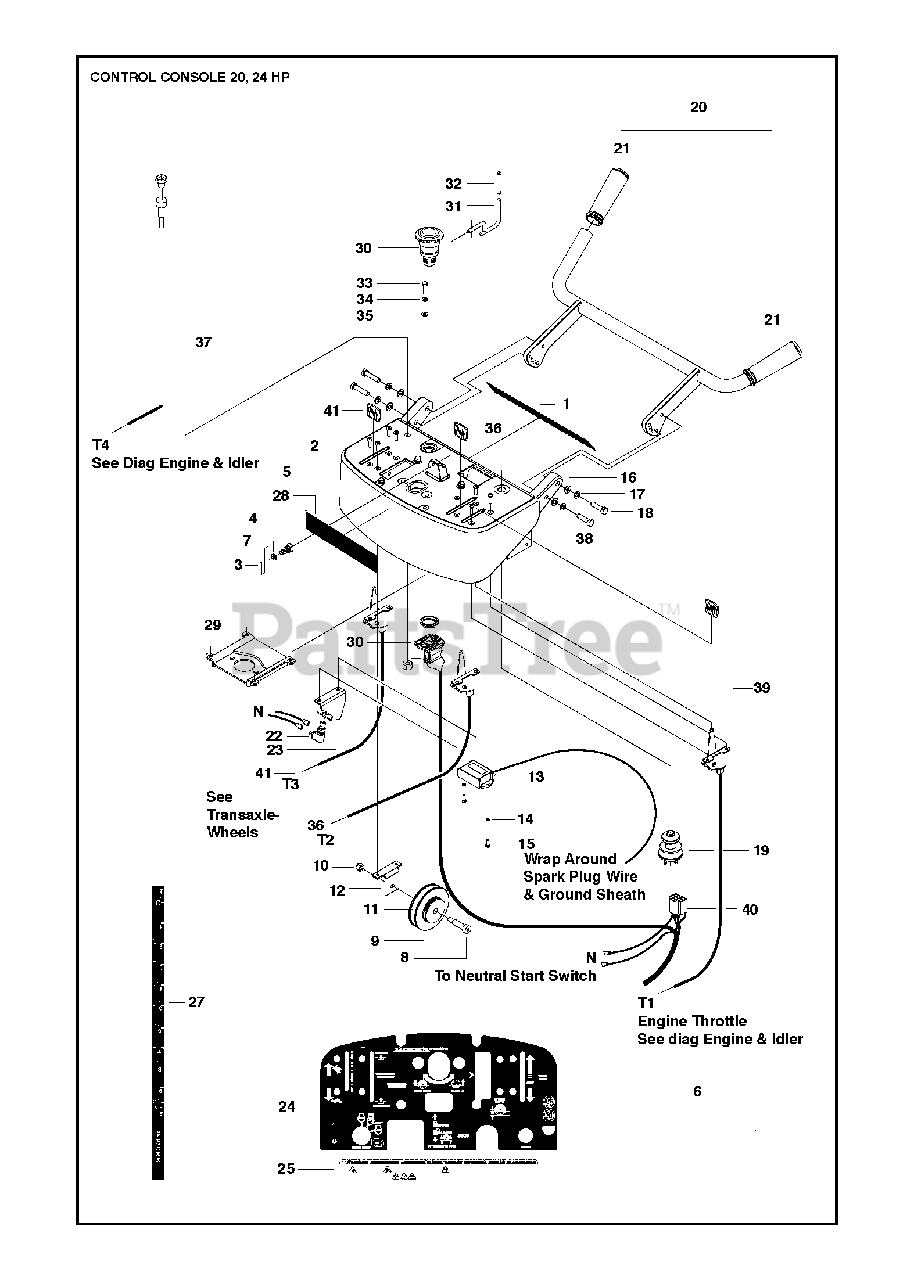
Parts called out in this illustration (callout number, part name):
14	SPRING WASHER 4.1X7.1
16	WASHER
17	SPRING WASHER
40	WIRING HARNESSIncludes stop switch and relays
